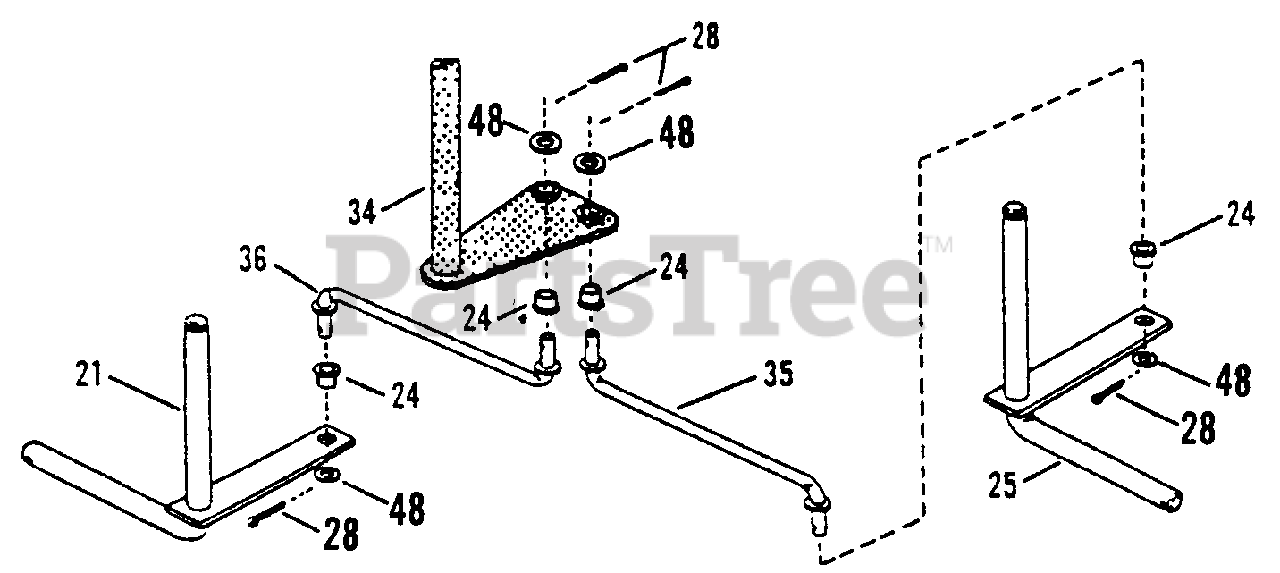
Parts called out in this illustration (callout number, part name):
21	PIN, Narrow King (Right Side)
24	BUSHING
25	PIN, Narrow King (Left Side)
28	PIN, 5/32 x 1" Cotter
34	SHAFT, Steering (Narrow Front End)
35	TIE-ROD, Left Side
36	TIE-ROD, Right Side
48	WASHER, 3/8" Flat
